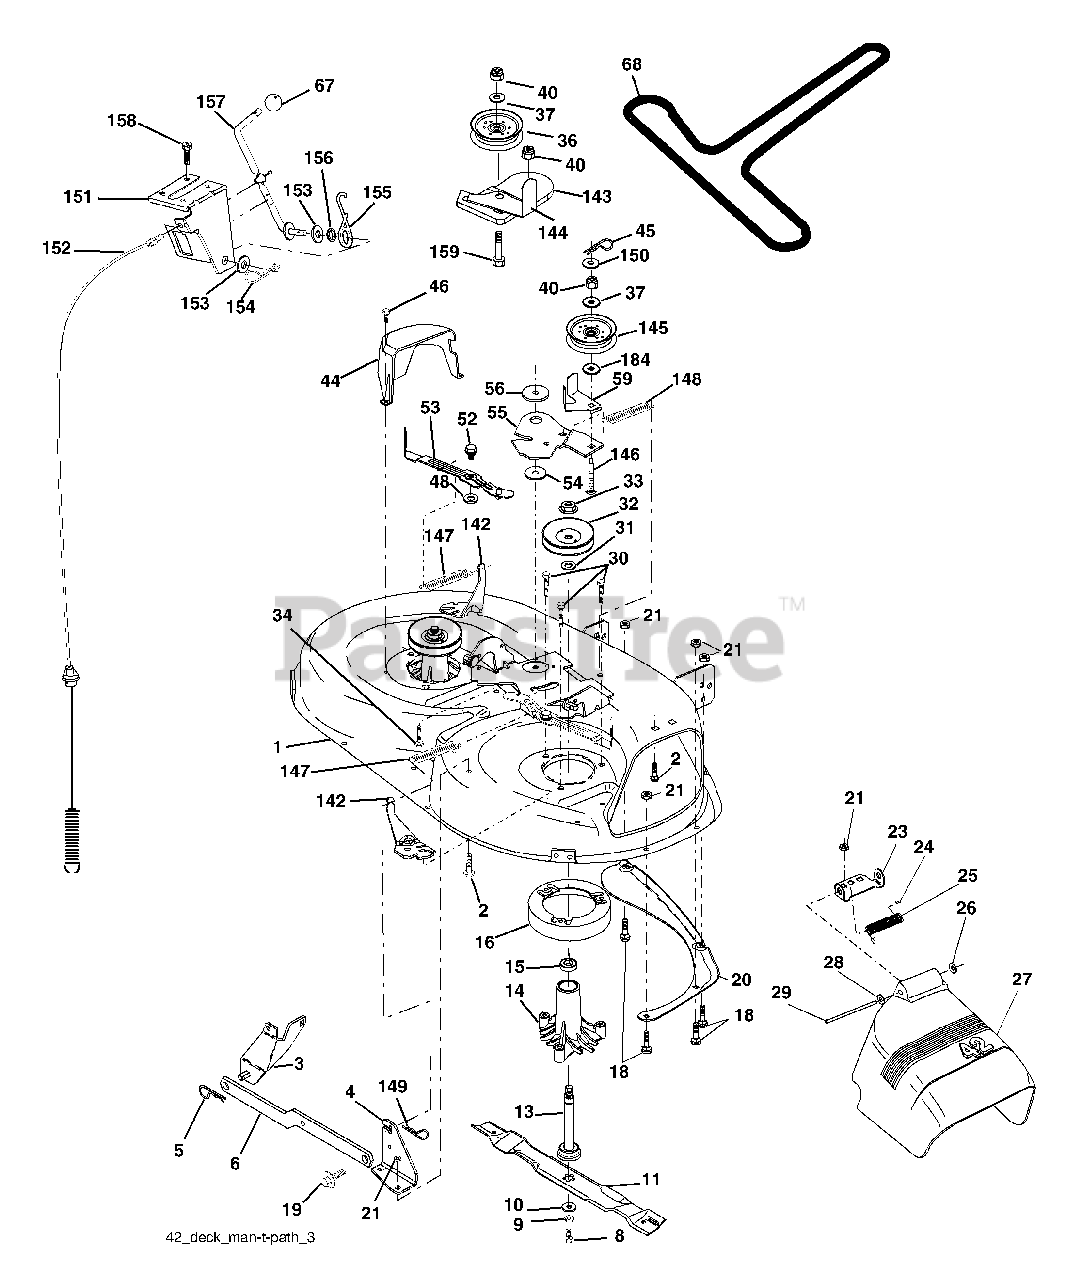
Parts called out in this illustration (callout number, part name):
1	Mower Deck Assembly, 42"
2	Bolt
3	Bracket Asm Fr. Sway Bar 3/42
4	Bracket Asm Deck 42" Sway Bar
5	Retainer Spring
6	Bar Sway Deck
8	Bolt 3/8-24 x 25 Grade 8 patched
9	Washer, Lock
10	Washer, Hardened
11	Blade, 42" Mulching Std
11	Blade, 42" Mulching Premium
11	Blade, 42" Hi-Lift
13	Shaft Assembly, Mandrel, Vented
14	Housing, Mandrel, Vented
15	Bearing, Ball, Mandrel
16	Stripper, Mandrel Deck
18	Bolt, Carriage 5/16-18 x 5/8
19	Bolt, Shoulder
20	Baffle, Vortex
21	Nut
23	Bracket, Deflector Mower 42"
24	Cap, Sleeve 80 x 112 Blk Mower
25	Spring, Torsion, Deflector 2 52
26	Nut, Push Phos & Oil
27	Shield, Deflector 42" Blk
28	Washer 11/32 x 5/8 x 16 Gauge
29	Rod, Hinge 42" 6 75 W/G
30	Screw Thdrol Washer Head
31	Washer, Spacer Mower Vented
32	Pulley, Mandrel
33	Nut, Toplock 9/16 Flange
34	Bolt
36	Pulley, Idler, Flat
37	Washer 13/32 x 13/16 x 16 Gauge
40	Nut
44	Guard, Mandrel, LH
45	Retainer
46	Screw, Thdrol 1/4-20 x 5/8 T
48	Washer, Hardened
52	Bolt, Shoulder 5/16-18 UNC
53	Arm Assembly, Pad, Brake
54	Washer, Hardened
55	Arm, Idler
56	Spacer, Retainer
59	Guard TUV Idler
67	Knob
68	V-Belt, 42" Mower
142	Arm Spring Brake Mower
143	Bracket Arm Idler 42"
144	Keeper Belt 42" Clutch Cable
145	Pulley Idler Flat
146	Bolt Carriage Idler
147	Spring Extension
148	Spring Return Idler
149	Retainer Spring Yellow
150	Washer 9/32 x 3/4 x 16 Ga.
151	Bracket Clutch Cable
152	Clutch Cable 42"
153	Washer Flat 3/8" Type B
154	Spring Retainer
155	Spring Retention LVR CLTCH CAB
156	Spacer Clutch Cable
157	Rod Clutch Cable 3/8"
158	Screw Hex Thd Cut 1/4-20 x 1/2
159	Bolt Rdhd Sqn 3/8-16 UNC x 1-3/4
184	Washer 13/32 x 7/8 x 10 Ga.
